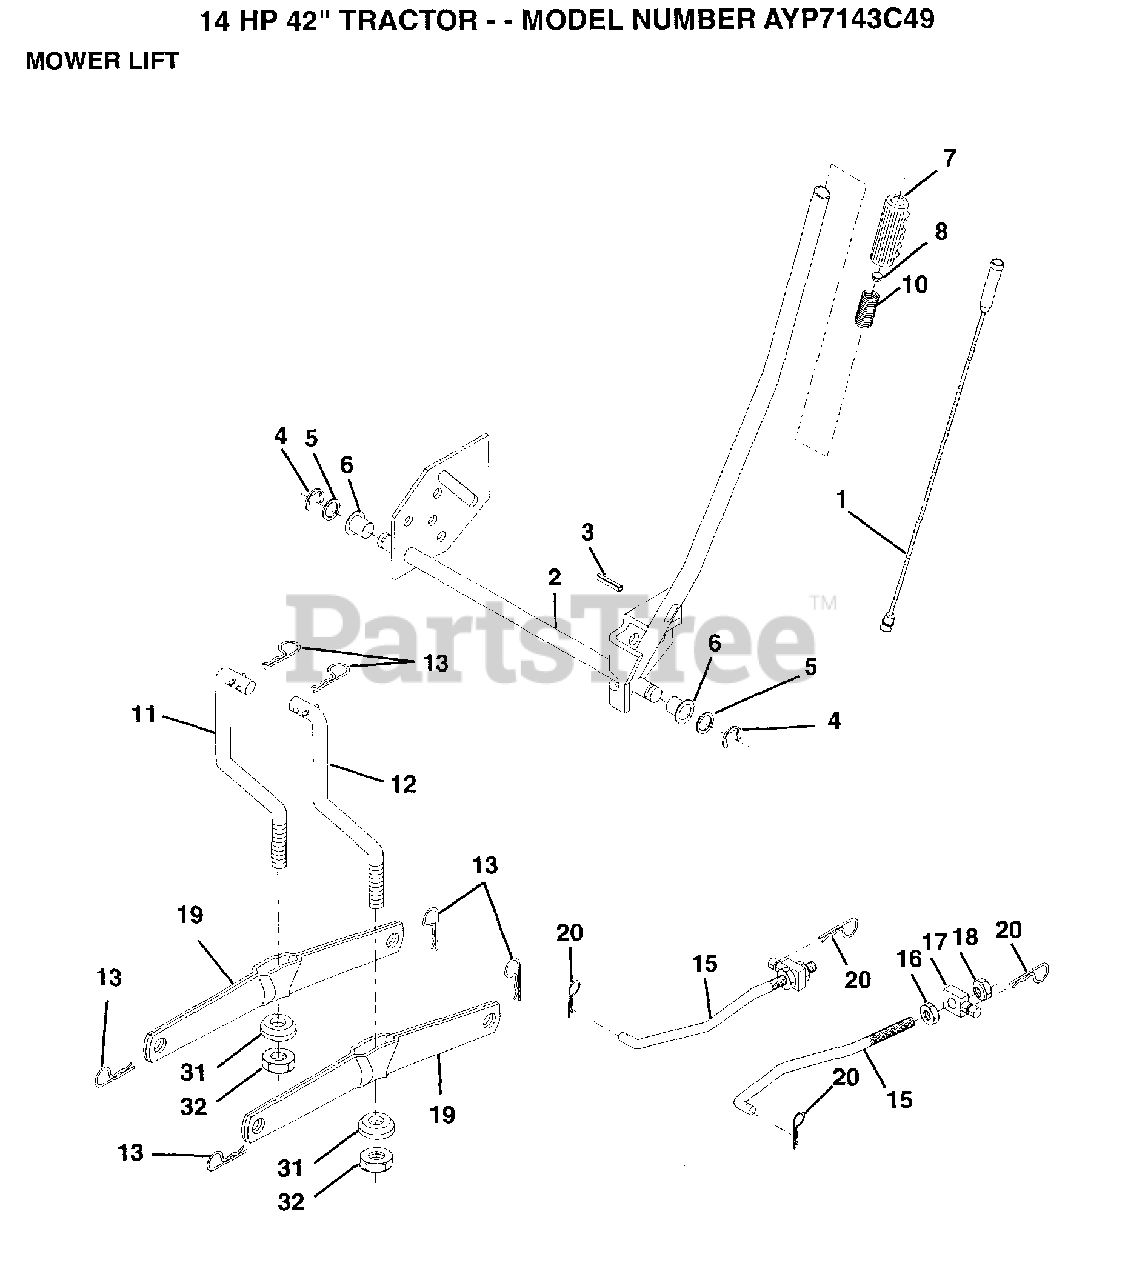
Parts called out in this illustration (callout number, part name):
1	WIRE ASM
3	PIN-GROOVE LT
5	WASHER
6	NYLON BEARING
7	GRIP
15	LINK.FRONT
16	NUT
17	TRUNION
18	NUT.LK.W/WSH.1/2.
19	ARM SUSP REAR
20	RETAINER.SPRING
31	BEARING PVT LH
32	NUT.LOCK.3/8-24
